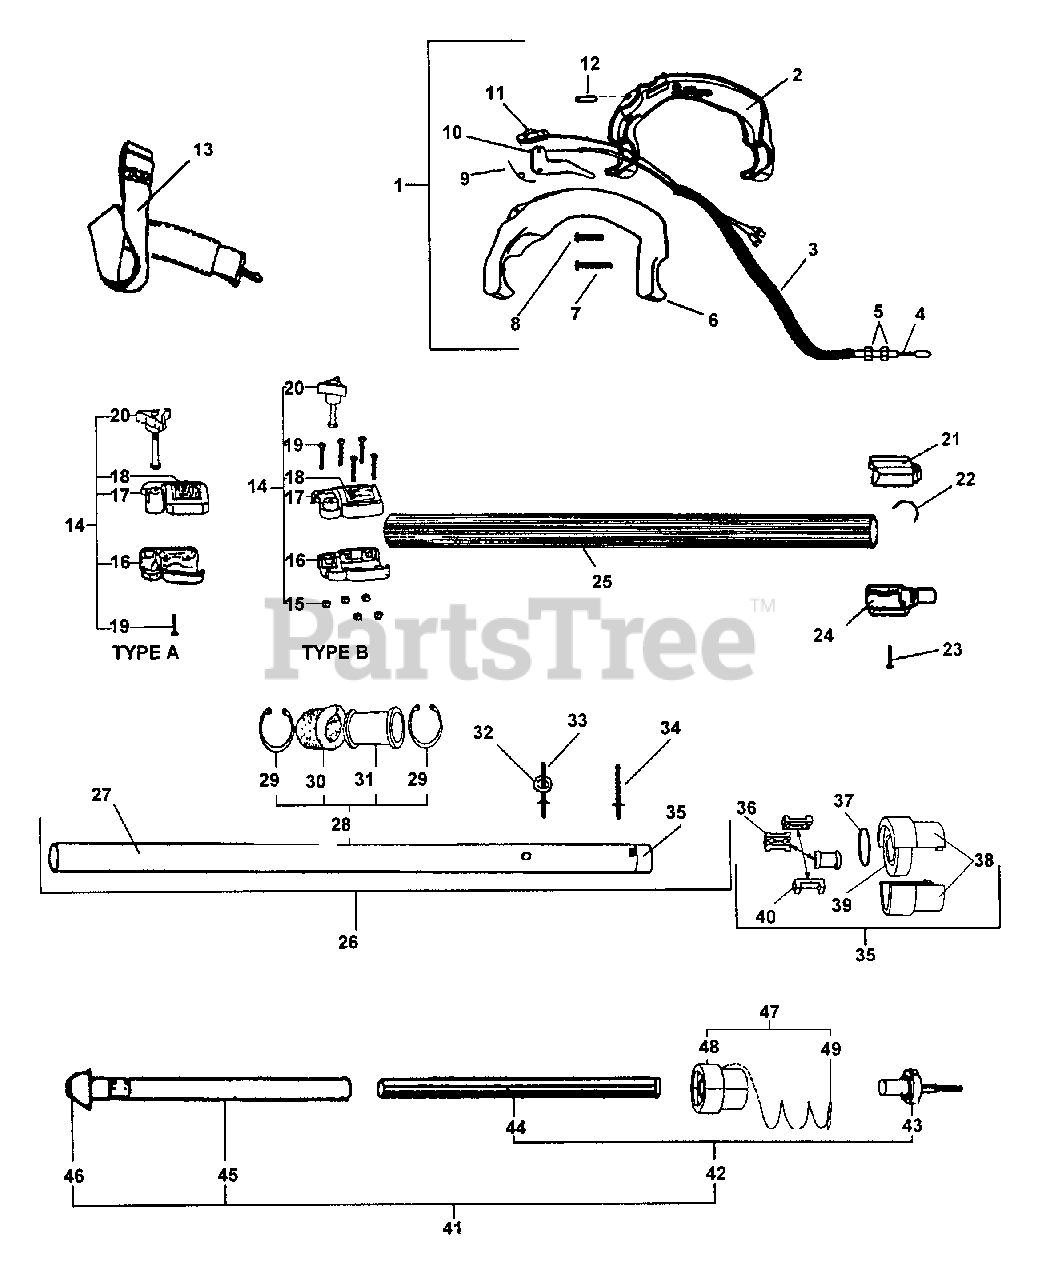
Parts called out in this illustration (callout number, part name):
1	HANDLE ASSY, REAR
2	HANDLE, REAR - RIGHT
3	TUBE, FLEXIBLE
4	CABLE, THROTTLE
6	HANDLE, REAR - LEFT
7	SCREW, TORX 10-24 UNC 1-1/4
8	SCREW, TORX
9	SPRING, TORSION
10	TRIGGER, THROTTLE
11	IGNITION SWITCH ASSY
12	PIN, LOCATING 0.17 OD×0.75 L
13	STRAP ASSY, SHOULDER
14	CLAMP ASSY
15	NUT, LOCK 10-24 UNC
16	COLLAR, LOWER
17	COLLAR, UPPER
18	LABEL - CAUTION
19	SCREW, TORX 10-24 UNC 1-1/4
20	THUMBSCREW
21	CAP, MAIN PIPE
23	SCREW, TORX 10-24 UNC 1-1/4
24	COUPLING, MAIN PIPE
25	PIPE, MAIN 1.5 ID×60" L
26	PIPE, MAIN
27	PIPE, MAIN - BLACK
28	DRIVESHAFT GUIDE ASSY
29	RING, SNAP
30	PAD, FOAM
31	GUIDE, DRIVESHAFT
32	WASHER, FLAT 5
35	HOLDER ASSY, BEARING
36	GUIDE, SHAFT - SMALL
37	WASHER, WAVE
38	HOLDER, BEARING
39	BEARING, BALL 6002 DDU
40	GUIDE, SHAFT - LARGE
41	DRIVESHAFT ASSY
42	DRIVESHAFT - LOWER
43	CONNECTOR, SHAFT
44	DRIVESHAFT
45	DRIVESHAFT
46	ADAPTER, UPPER DRIVE SHAFT
47	BUSHING ASSY, FLOATING
48	SPRING, COMPRESSION
49	BUSHING, FLOATING
